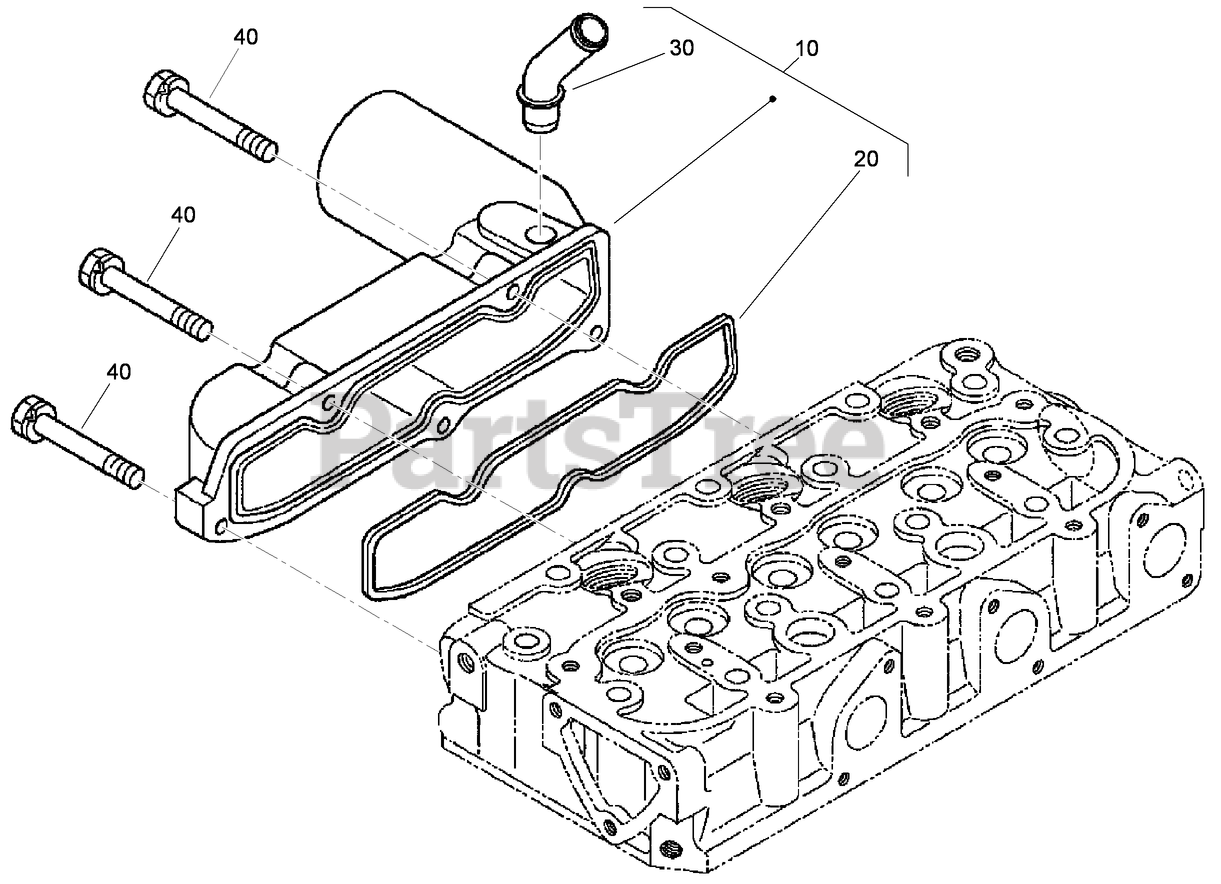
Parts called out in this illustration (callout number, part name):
10	INLET MANIFOLD ASM
20	GASKET-MANIFOLD, INTAKE
30	PIPE-BREATHER
